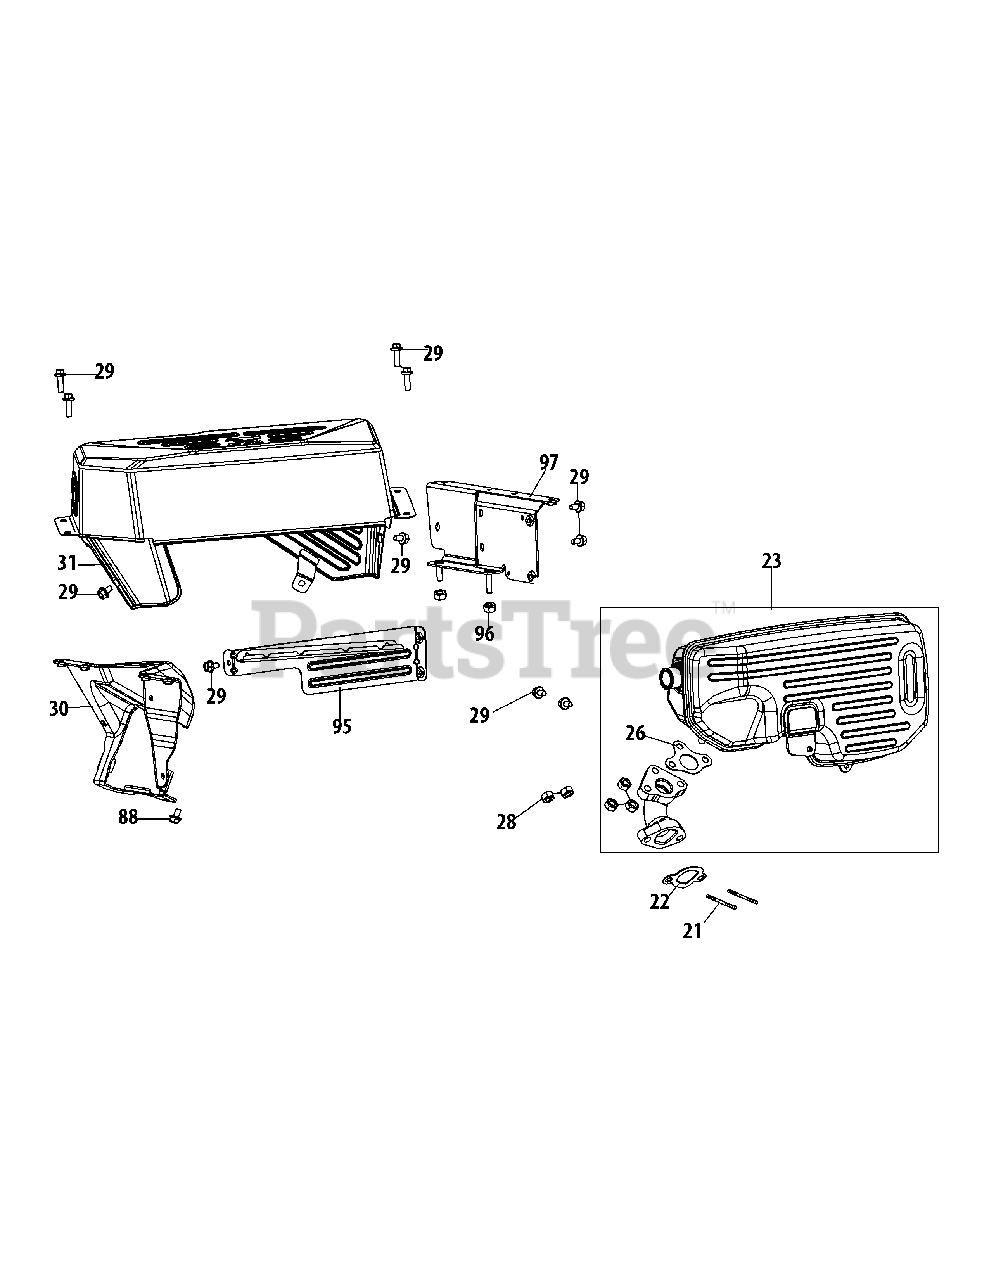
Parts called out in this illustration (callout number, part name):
21	Stud M8×36
22	Muffler Gasket
23	Muffler Assembly
26	Gasket, Muffler
28	Nut M8
29	Bolt M6×12
30	Front Bracket, Fuel Tank
31	Muffler Guard
88	Bolt M6×16
95	Fuel Tank Insulator
96	Flange Nut M6
97	Fuel Tank Bracket
